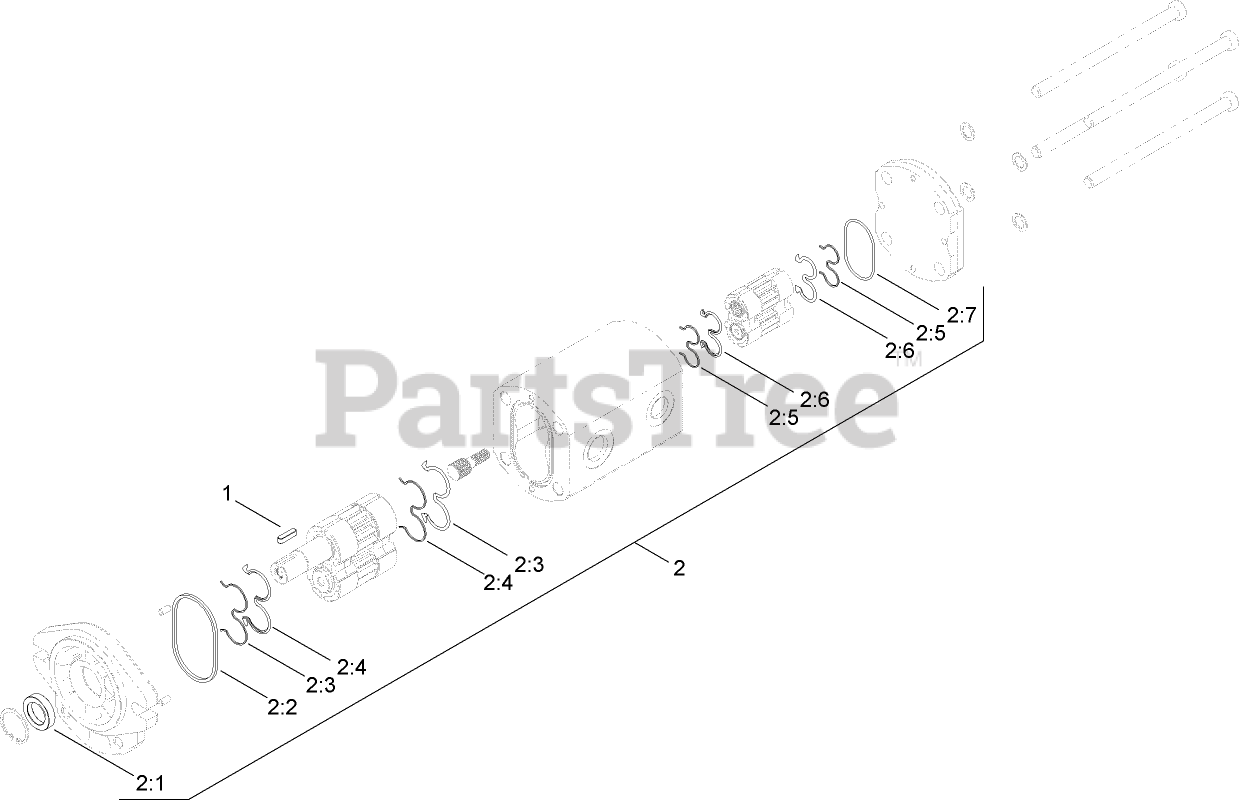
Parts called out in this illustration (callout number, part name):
1	KEY-SQUARE
2	SEAL KIT
2:1	Seal-Shaft
2:2	Seal-Square
2:3	Ring-Backup
2:4	SEAL-GEAR
2:5	Ring-Backup
2:6	SEAL-GEAR, REAR
2:7	O-Ring
